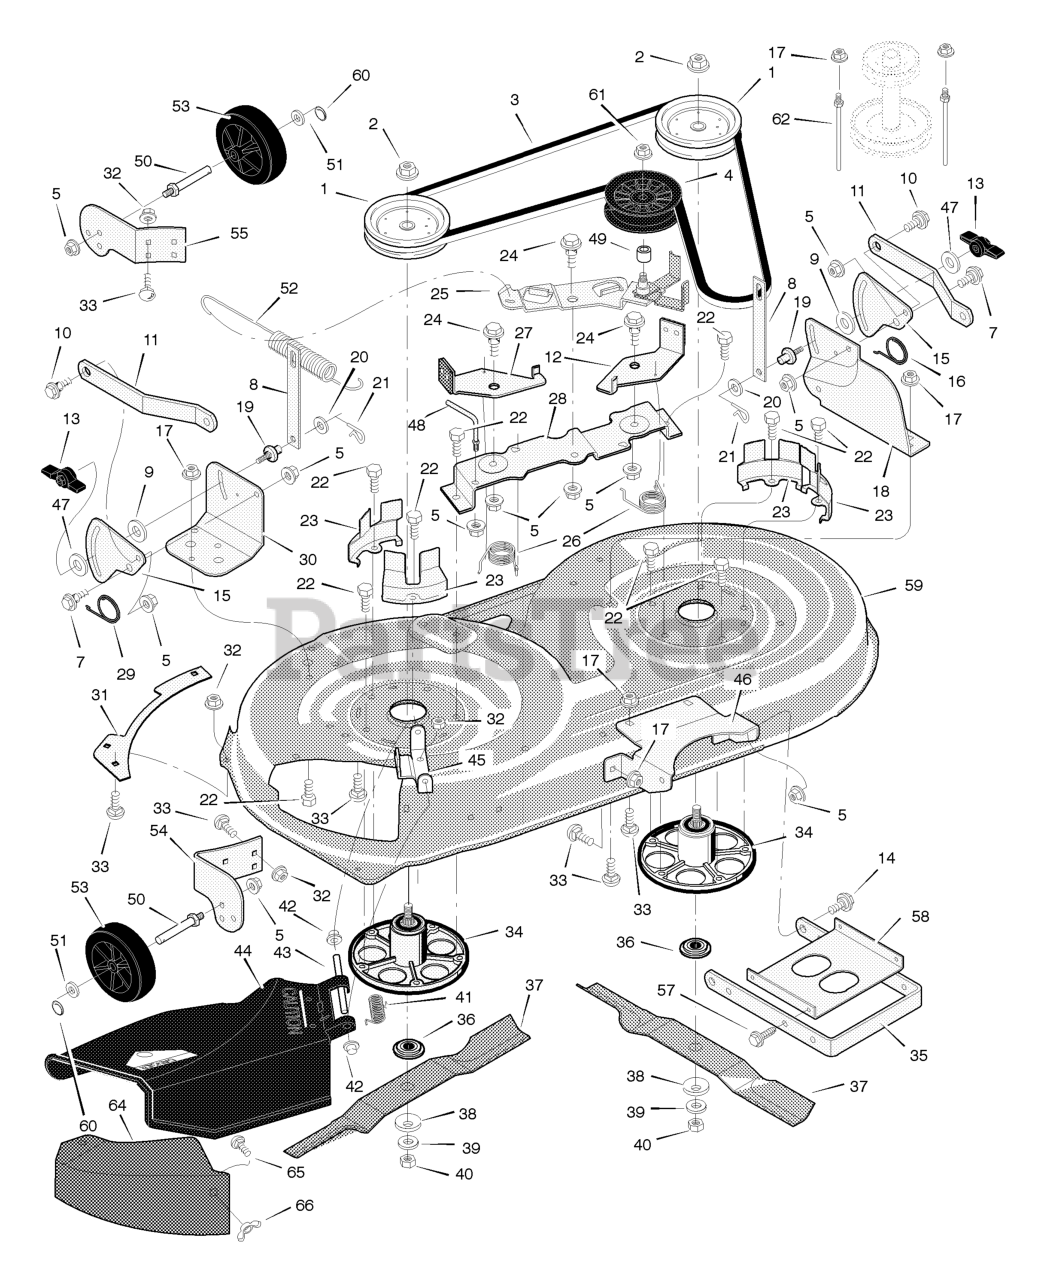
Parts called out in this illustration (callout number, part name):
1	Pulley, Jackshaft
2	Nut, Hex
3	Belt, Mower Drive
4	Pulley, Idler
5	Nut, Flange
7	Bolt, Shoulder
8	Link, Lift
9	Pad, Friction
10	Bolt, Shoulder
11	Bracket, Suspension
12	Pad Assembly, Left Brake
13	Knob
14	Bolt, Shoulder
15	Plate, Suspension
17	Nut, Flange
18	Bracket, Suspension
19	Pin, Hanger
21	Pin, Hair
22	Bolt
23	Cover, Pulley
24	Bolt, Shoulder
25	Arm, Idler
27	Pad Assembly, Right Brake
28	Bracket, Brake
30	Bracket, Suspension
32	Nut, Flange
33	Bolt, Carriage
34	Mandrell Housing
35	Bracket, Suspension
36	Adapter, Blade
42	Cap, Push On
43	ROD, Deflector
44	Deflector Assembly
45	Bracket, Deflector Hinge
46	Bracket, Front Hanger
48	Guide, Belt
50	BOLT, Gauge Wheel
52	Spring, Extension
53	Wheel, Gage
54	Bracket, Right Wheel
55	Bracket, Left Wheel
59	Housing, Blade, Complete (NO LONGER AVAILABLE)
59	Housing, Blade (Housing Only)
60	Ring, Locking
61	Nut, Flange
62	Guide, Belt
64	Cover, Mulch
65	Bolt, Carriage
66	Wingnut
